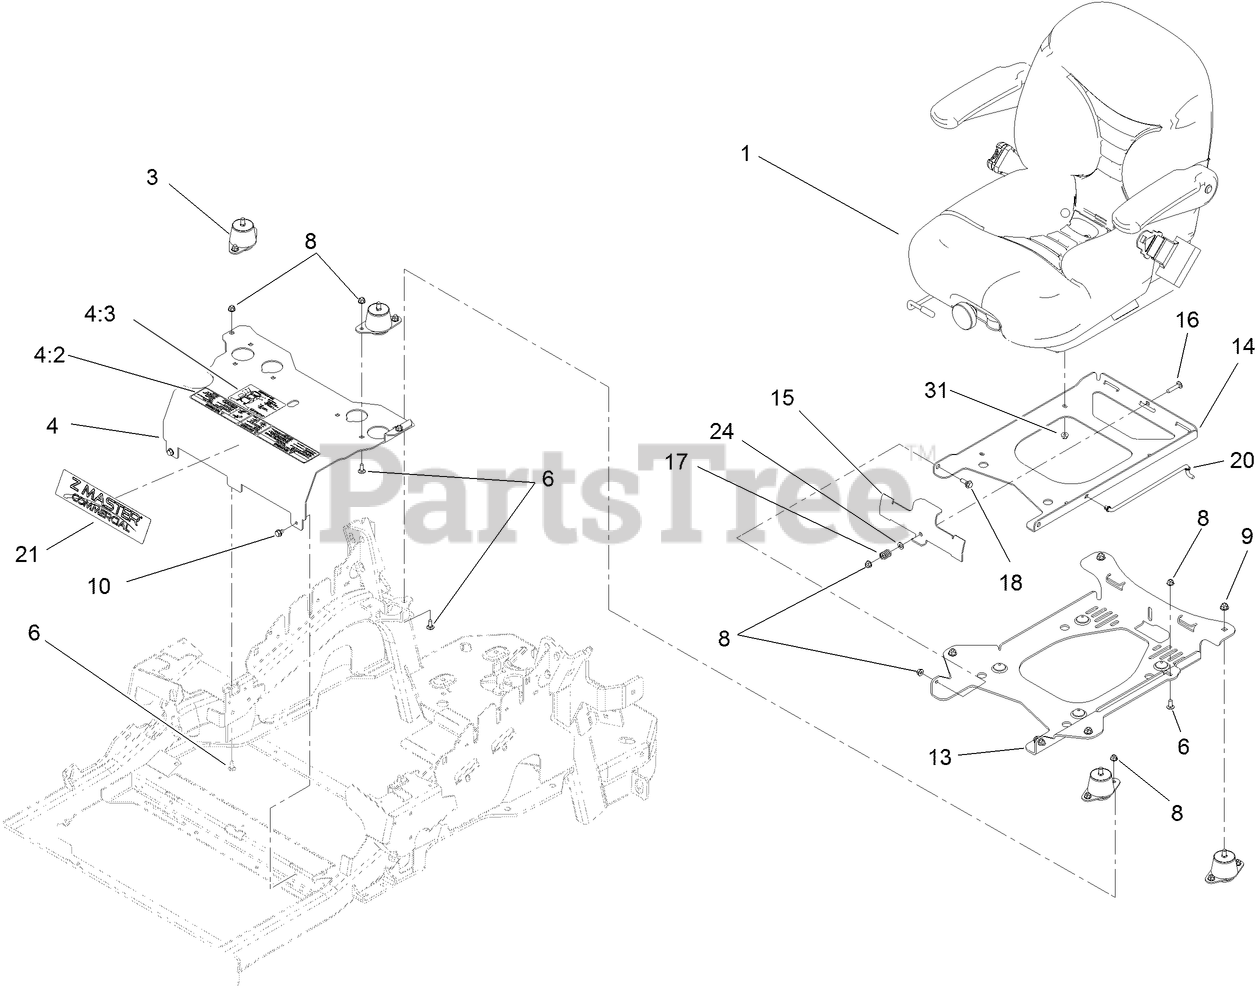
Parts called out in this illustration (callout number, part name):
1	SUSPENSION SEAT ASM
3	ISOLATOR-SEAT
4	MOUNT-SEAT
4:2	DECAL-CONSOLE
4:3	DECAL-SERVICE AID
6	SCREW-CARR
8	NUT-HF, NI
9	NUT-HF, NI
10	SCREW
13	PLATE-SUPPORT, SEAT TILT
14	PLATE-FRAME, SEAT TILT
15	PLATE-LATCH, SEAT
16	BOLT-CARR
17	SPRING-COMPRESSION
18	SCREW-SHOULDER
20	ROD-PROP
24	WASHER-PLAIN
31	NUT-HF
